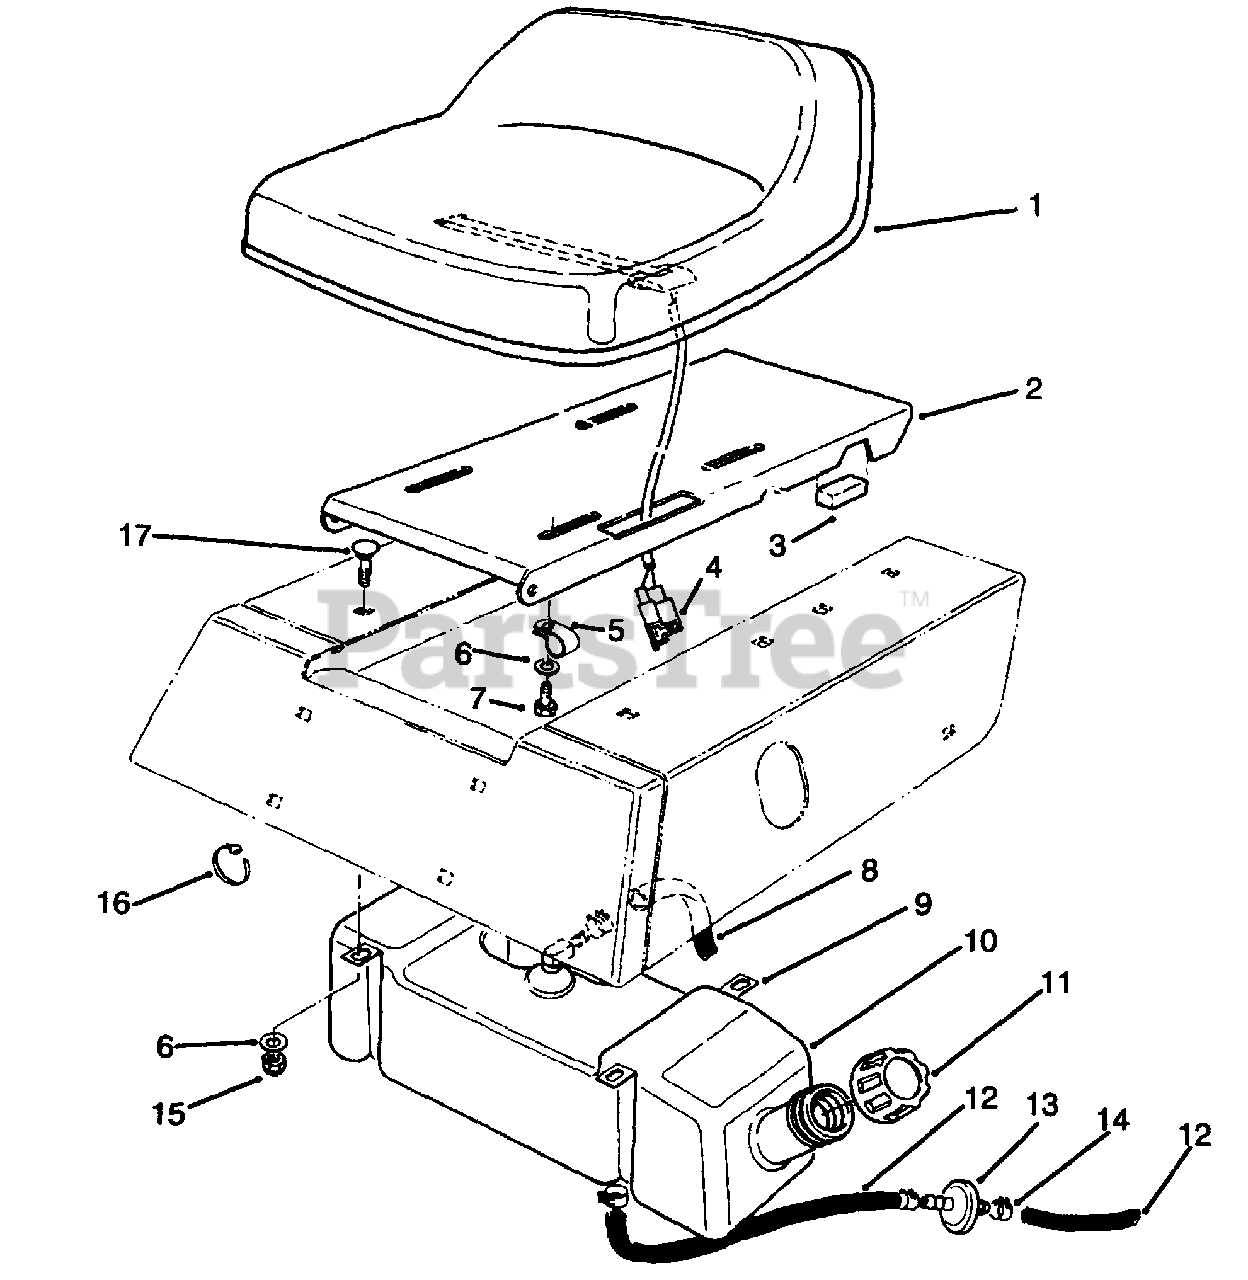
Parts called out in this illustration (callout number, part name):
3	Pad-Isolator
4	Switch-Seat
6	Washer-Flat
7	Screw-Cap Hex. Hd.
8	Hose-Gas
9	Strap-Tank, Gas
10	Tank-Gas
11	Assembly-Cap, Gas
12	Hose-Gas
14	Clamp-Hose
15	Nut-Lock
16	Tie-Cable
17	Bolt-Carriage
